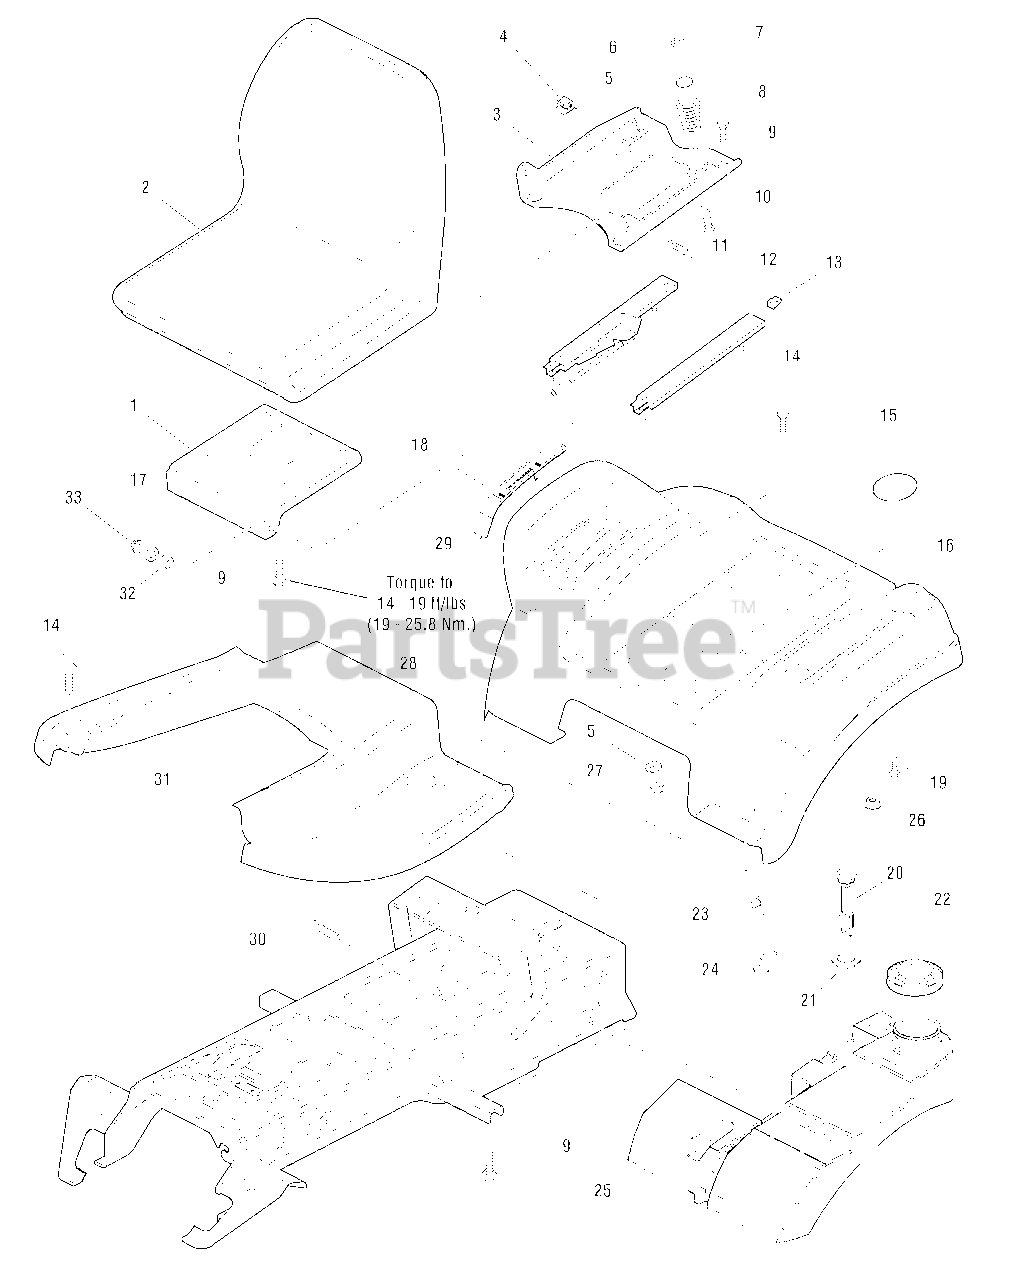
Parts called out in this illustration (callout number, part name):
1	BRACKET, Seat
2	SEAT, 15" Back, Simplicity Logo
3	SUPPORT, Seat
5	WASHER, Spring
6	SPRING, Compression
7	NUT, Hex Lock ESNA, 5/16-18
8	SPRING, Compression
9	CAPSCREW, Hex Head Dog Point, 5/16-18 x 3/4
10	CARRIAGE BOLT, 5/16-18 x 2
11	CARRIAGE BOLT, 3/8-16 x 1
12	SLIDE, Seat, (2 Piece Set)
13	NUT, Speed, 5/16-18
14	CAPSCREW, Hex Head Taptite, 5/16-18 x 5/8
15	PLUG, Hole Black
16	POD, LH, w/Cup holder
17	WASHER
18	COVER, Cruise, w/Symbols
19	CAPSCREW, Hex Head, 1/4-20 x 5/8
22	CAP, Gas
23	TUBE & ELBOW ASSEMBLY, with Screen, Fuel
26	NUT, Hex Whiz Lock, 5/16-18
27	NUT, Hex KEPS, 5/16-18
28	DECK, Seat, Red
29	POD, RH, w/2 Slots
30	CAPSCREW, Hex Head Flange Lock, 5/16-18 x 5/8
31	TUNNEL, Footrest
33	NUT, Hex Flange Lock, 3/8-16
